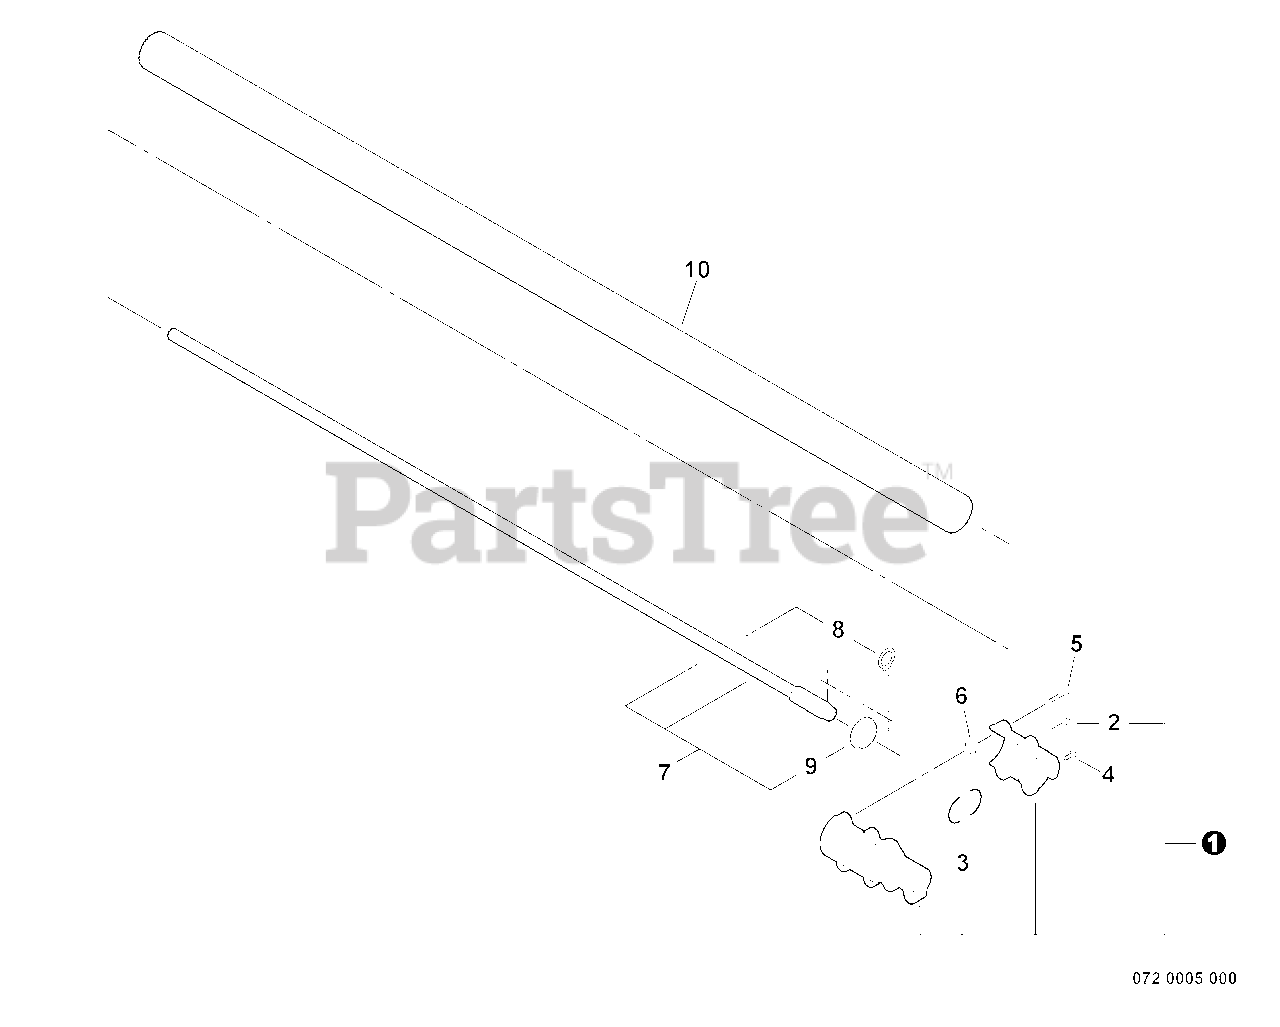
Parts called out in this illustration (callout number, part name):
1	COUPLING ASSY
2	SCREW - 5X20
3	CUSHION
4	SCREW - 5X14
5	SCREW - 5X20
6	WASHER - 5
7	DRIVESHAFT ASSY - LOWER
8	RING, RETAINING
9	BEARING, BALL - 6002
10	PIPE, MAIN - ORANGE
